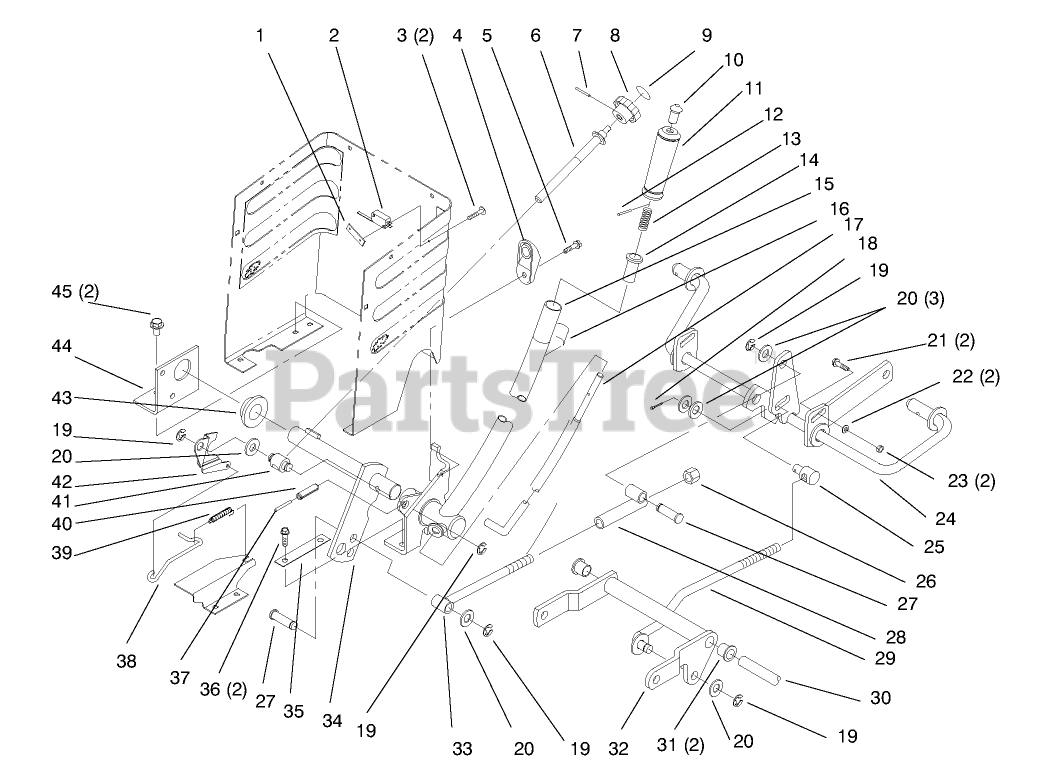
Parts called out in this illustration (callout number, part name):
1	NUT-SPEED
2	SWITCH-MICRO
3	SCREW-PPHTF
4	WEDGE - HOC
5	SCREW-HWH
7	PIN-SPIROL
10	TIP-ROD
11	GRIP-HANDLE
12	PIN-SPIROL
13	SPRING-COMPRESSION
14	RETAINER-SPRING
15	LEVER-LIFT
16	DECAL-LIFT
17	ROD-LEVER, LIFT
18	PIN-COTTER
19	RING-RETAINING, EXTERNAL
20	WASHER-FLAT
21	BOLT-CARR
22	WASHER-FLAT
23	NUT-LOCK, NI
24	SHAFT-GAGE
26	NUT-LOCK, NI
31	BUSHING-FLANGE
32	ARM-PIVOT
34	SHAFT-LIFT
36	SCREW-HWHTF
37	PIN-SPRING
38	ROD - HOC INDICATOR
39	SPRING - EXTENSION
40	PIN-ROLL
42	PLATE - HOC GAGE
43	BEARING-FLANGE
44	BRACKET-PIVOT, LINKAGE
45	SCREW-HWHTF
